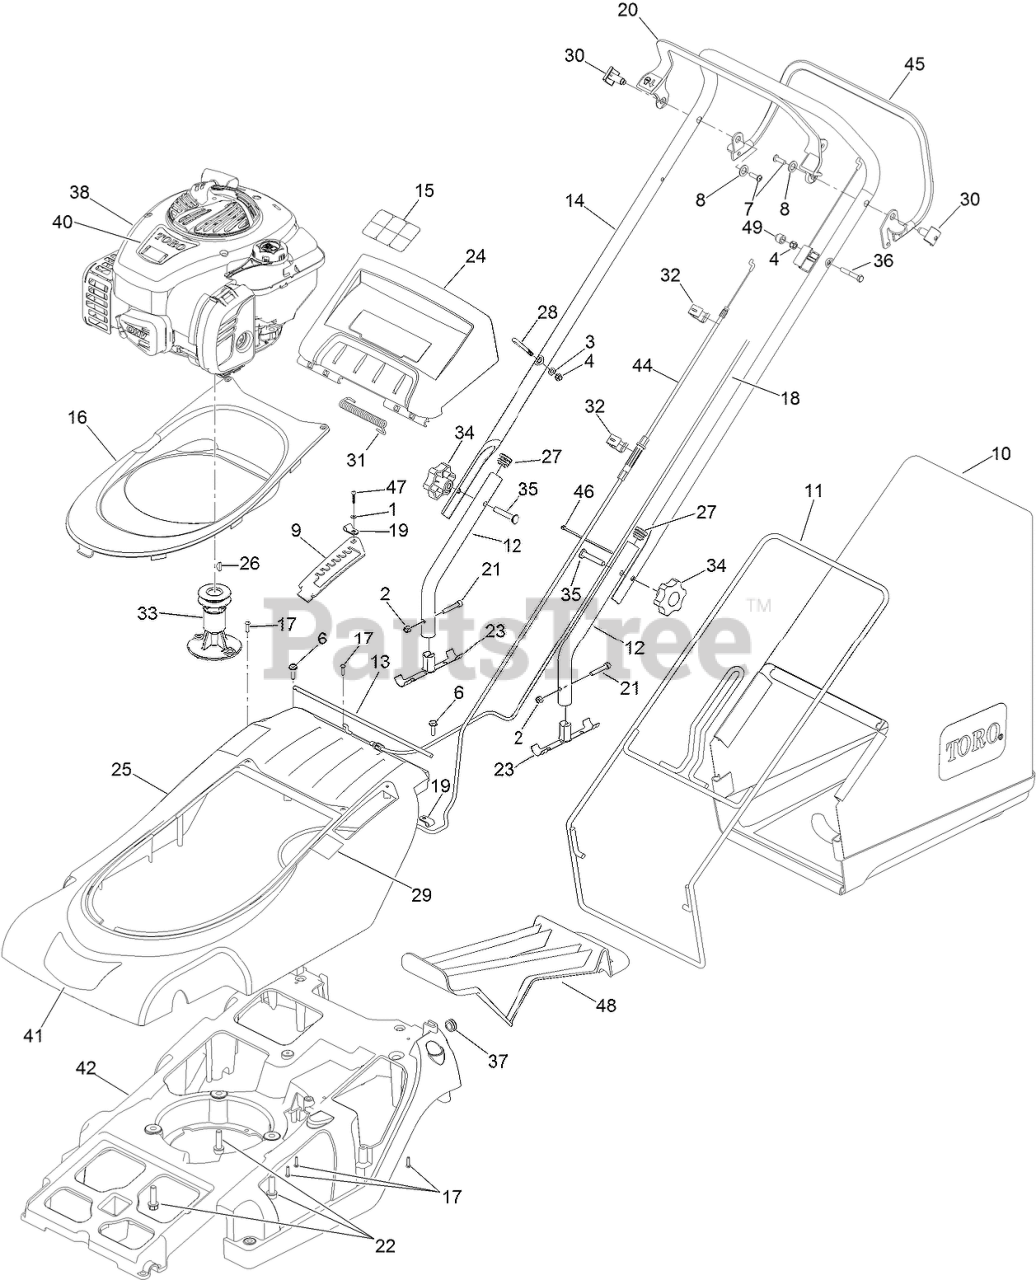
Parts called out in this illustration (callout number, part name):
1	WASHER
2	NUT-NYLOC
3	WASHER-PLAIN
4	NUT-NYLOC
6	SCREW-TAPTITE
7	SCREW
8	WASHER-NYLON
9	PLATE-HOC
10	GRASSBAG
11	FRAME-GRASSBAG
12	HANDLEBARS-LOWER
13	BAR-HINGE
14	HANDLEBARS
15	DECAL-SAFETY
16	MOULDING-TRIM
18	CABLE-BRAKE, ENGINE
19	CLIP-P
22	SCREW-TAPTITE, UNC
23	PLUG-HANDLEBAR
24	MOULDING-DEFLECTOR, REAR
25	TOP-COVER
26	KEY-WOODRUFF
27	PLUG-TUBE
28	GUIDE-ROPE
29	DECAL-HOC
30	PIN-PIVOT
31	SPRING-DEFLECTOR
32	GUIDE-CABLE
33	CARRIER-BLADE
34	KNOB-HANDLEBAR
35	BOLT-HANDLEBAR
36	SCREW-HH
37	GROMMET-RUBBER
40	DECAL-ENGINE
41	DECAL-RECYCLE
44	CABLE-CLUTCH, AUTO-DRIVE
46	TIE-CABLE
47	SCREW-PLASTITE
48	PLUG-MULCHING
49	CAP-PLASTIC
